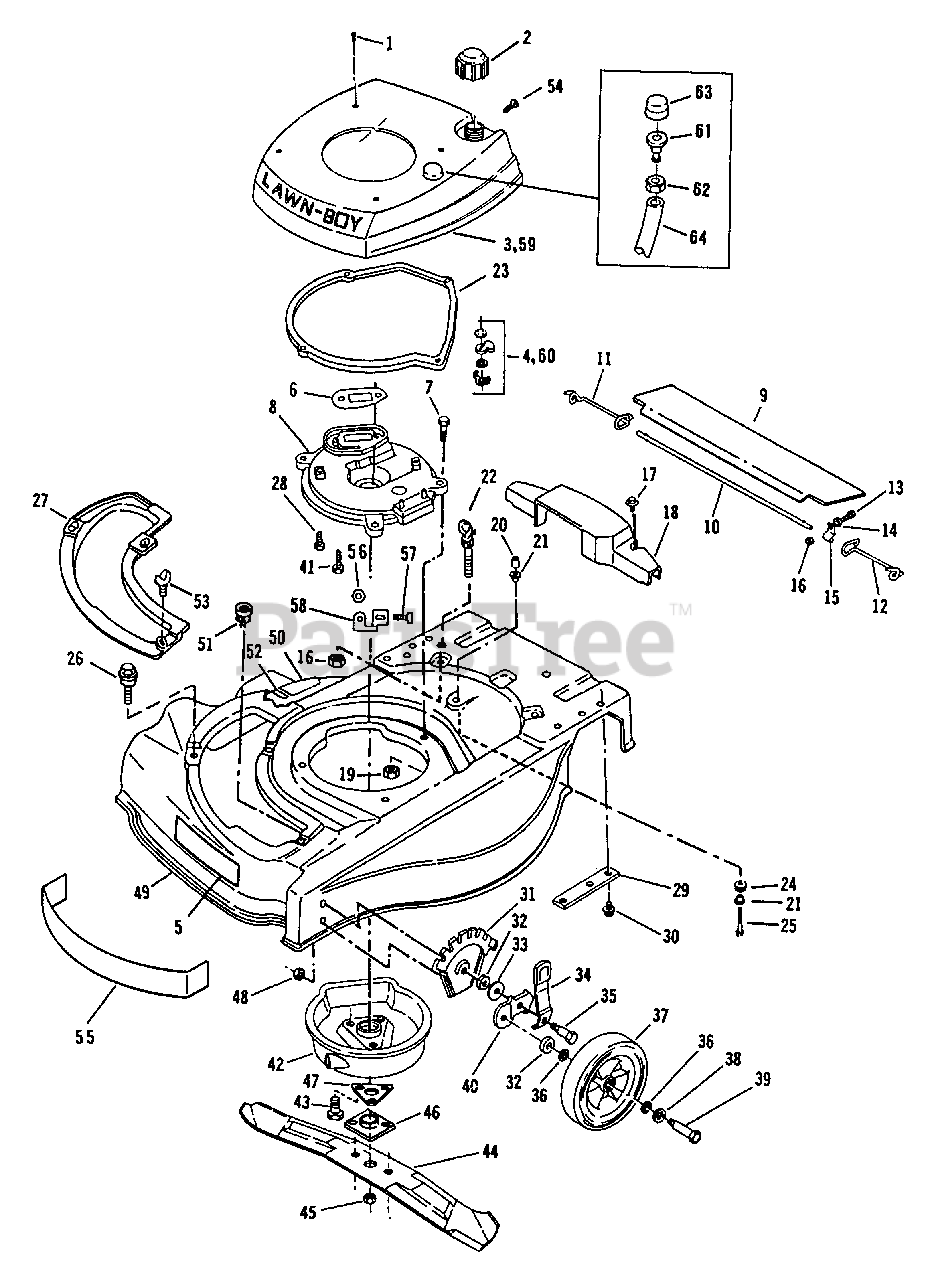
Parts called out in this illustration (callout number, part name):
1	Screw
2	Fuel Cap Assembly
5	Decal-Headliner
6	Gasket
7	Screw-Muffler Plate to Housing
8	Plate-Muffler
9	Shield-Trailing
10	Rod-Trailing Shield
11	Spring-R.H.
12	Spring-L.H.
13	Screw-Trailing Shield
14	Washer-Trailing Shield
15	Clamp
16	Nut-Trail. Shield and Eyebolt
17	Screw-Axle Cover Mounting
18	Cover-Drive Axle
19	Nut-Muffler Plate to Housing
20	Spacer
21	Spacer
22	Eyebolt
23	Spacer-Shroud to Base
24	Grommet
25	Screw-Transmission to Housing
26	Screw-Plate and Chute Mouting
27	Cover Plate
28	Screw-Muffler Plate to Cylinder
29	Plate-Handle Bracket Support
30	Screw-Handle Bracket to Housing
31	Plate-Height Adjust
32	Washer
33	Washer-Wheel Mounting Bracket
34	Knob and Spring Assembly
35	Bolt-Shoulder
36	Washer-Felt
37	Wheel-Front
38	Washer-Wheel Bolt Head
39	Bolt-Wheel-Front
40	Bracket-Wheel Height Adjust
41	Screw-Muffler Plate to Cylinder
42	Muffler Cover Assembly
43	Screw-Crankshaft Support
44	Blade-21"
45	Nut-Blade
46	Collar and Plate Assembly
47	Support-Crankshaft
48	Nut
49	Housing Assembly
50	Decal-Blade Contact Warning
51	Grommet
52	Decal-Discharge Area
53	Wing Screw
54	Screw-Shroud to C.D. Bracket
55	Baffle Front
56	Nut-Baffle Bracket
57	Screw
58	Bracket-Baffle
59	Shroud, Tank and Valve Assembly
60	Fuel Valve Assembly
61	Base-Primer
62	Locknut
63	Primer Bulb
64	Tubing-Primer
